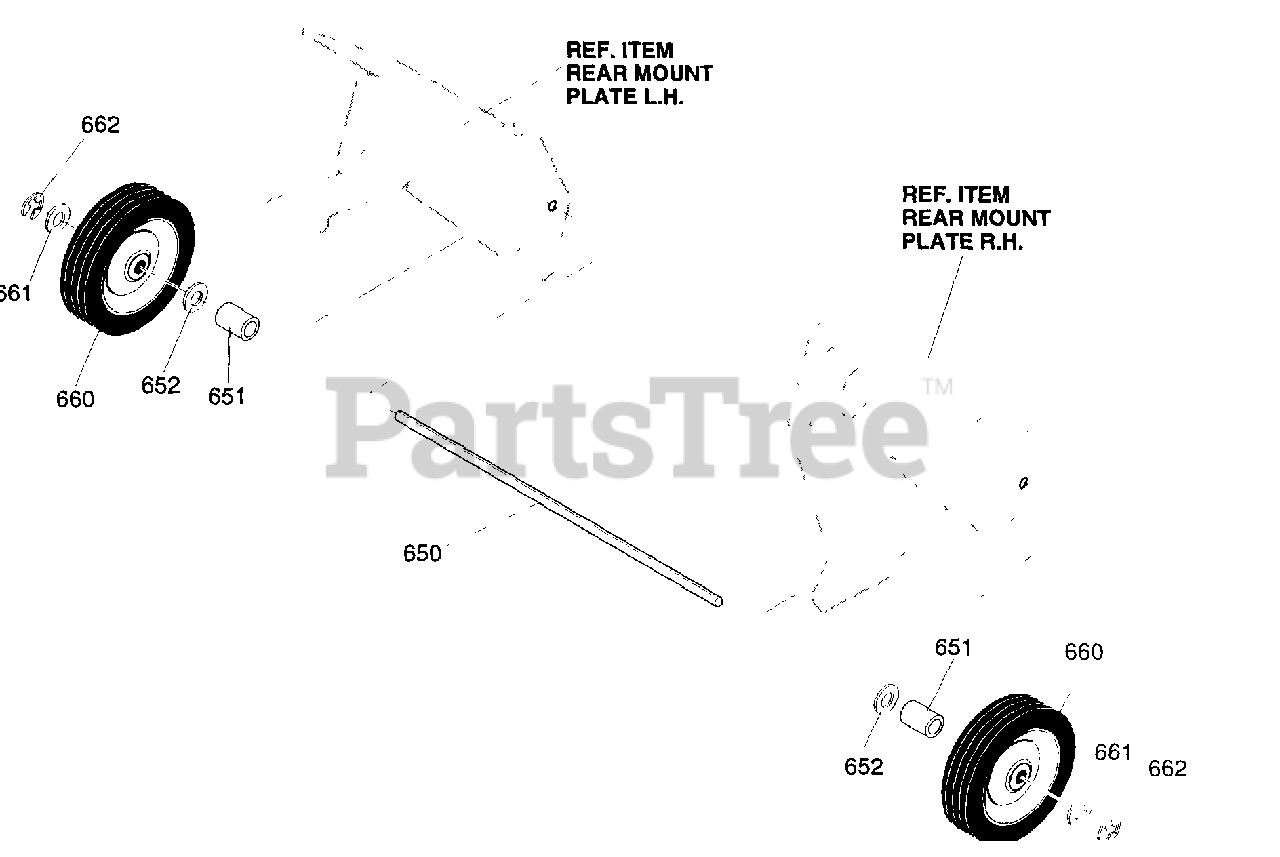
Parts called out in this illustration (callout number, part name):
650	SHAFT, AXLE 5/21 SC
651	SPACER, SLEV 407 X .63 X .440
652	FLATWASHER .406 X .81 X .065
660	TIRE & RIM 8 X 1.75
661	FLATWASHER .406 X .81 X .065
662	RING, RET E .30 X .04
